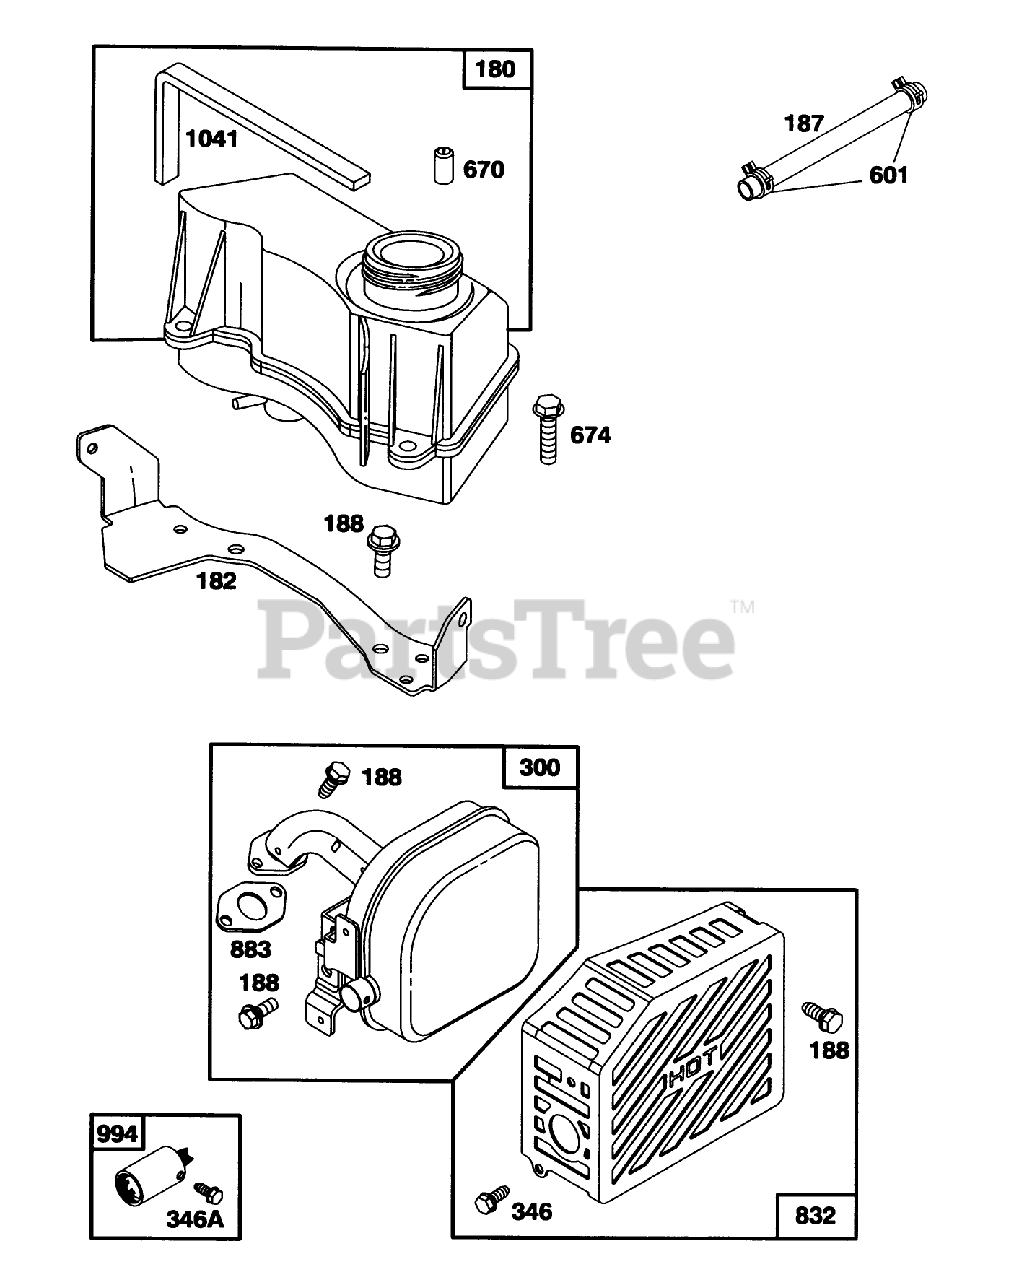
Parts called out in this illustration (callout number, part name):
180	TANK ASSY - FUEL
188	SCREW - SEM
300	MUFFLER - EXHAUST
346	SCREW - SELF-TAPPING
601	CLAMP - CL PIPE
670	SPACER
674	SCREW - HEX HEAD
